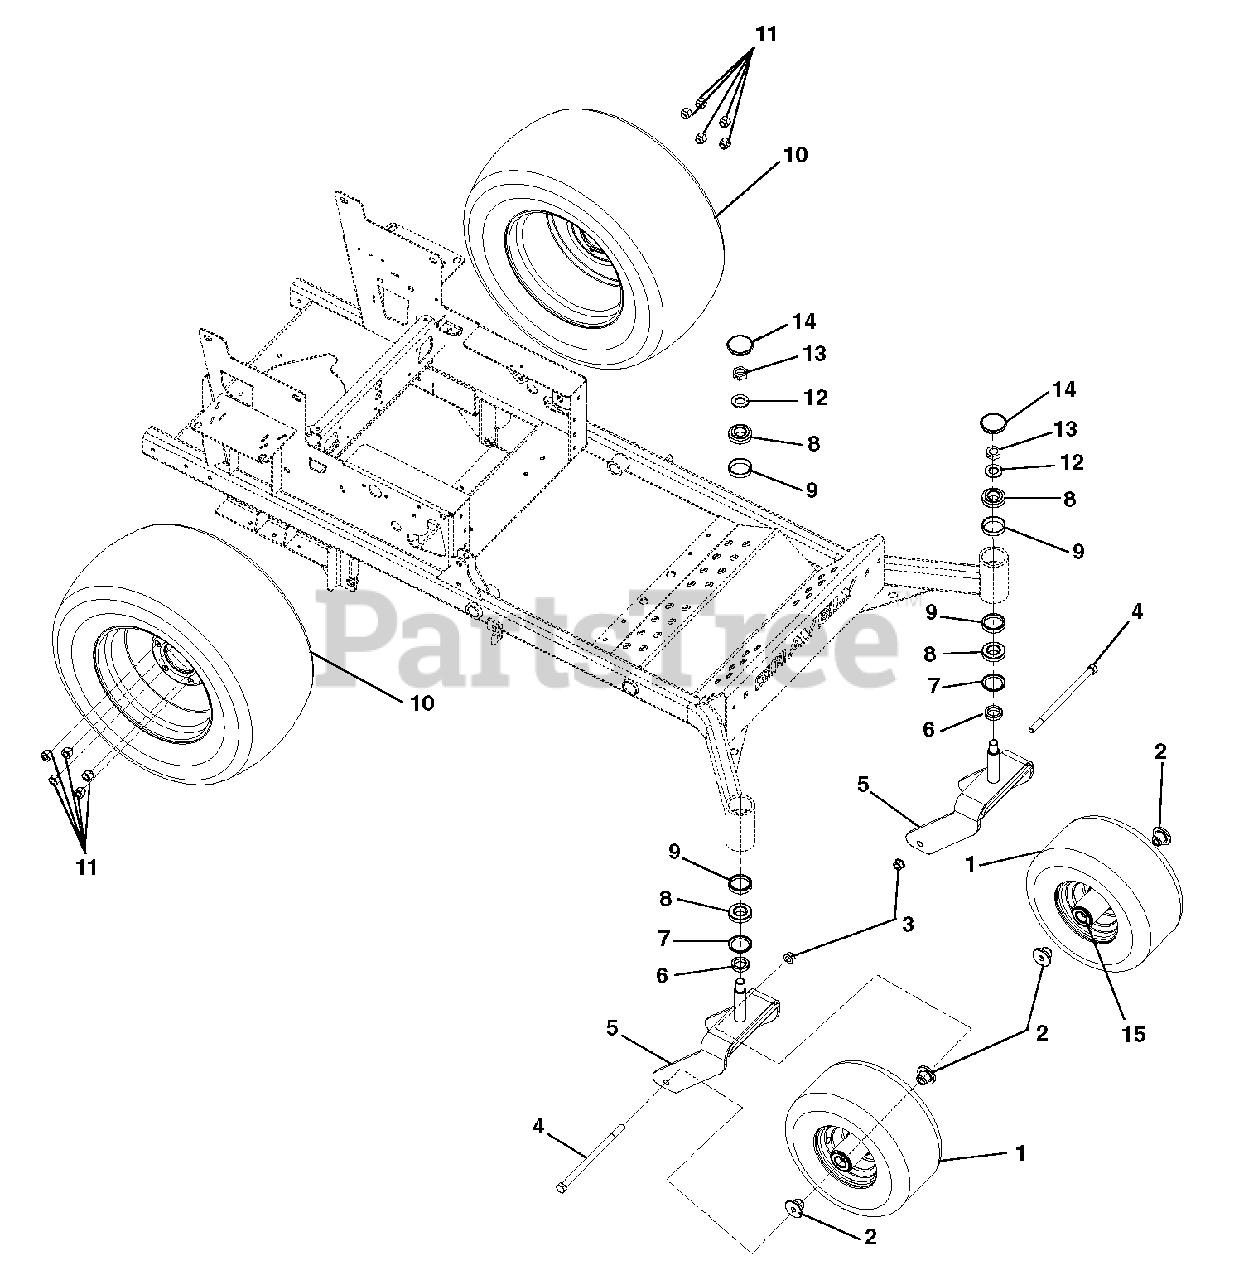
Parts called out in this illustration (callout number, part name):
1	Tire/Wheel Assembly, 13 x 6.50-6
2	Spacer, Front Wheel
3	Nut, .50-13 Nyloc Flange
4	Bolt, Hex .50-13 X 9.00 Grade 5
6	Spacer 1.258 x 1.75 x .550
7	Seal, Oil 1.75 x 2.332 x .312
8	Bearing, Cone 1.25 x .66
9	Bearing, Cup 2.328 x .465
10	Tire/Wheel Assembly, 23 x 10.00-12
11	Nut, Wheel .50-20 13/16 Across Flats Automotive Type
12	Washer, Flat Steel .812 x 2.00 x .148
13	Nut, Jam Center-Lock .75-16
14	Cap, Dust
15	Bearing, 25MM ID x 52MM OD x 15MM
